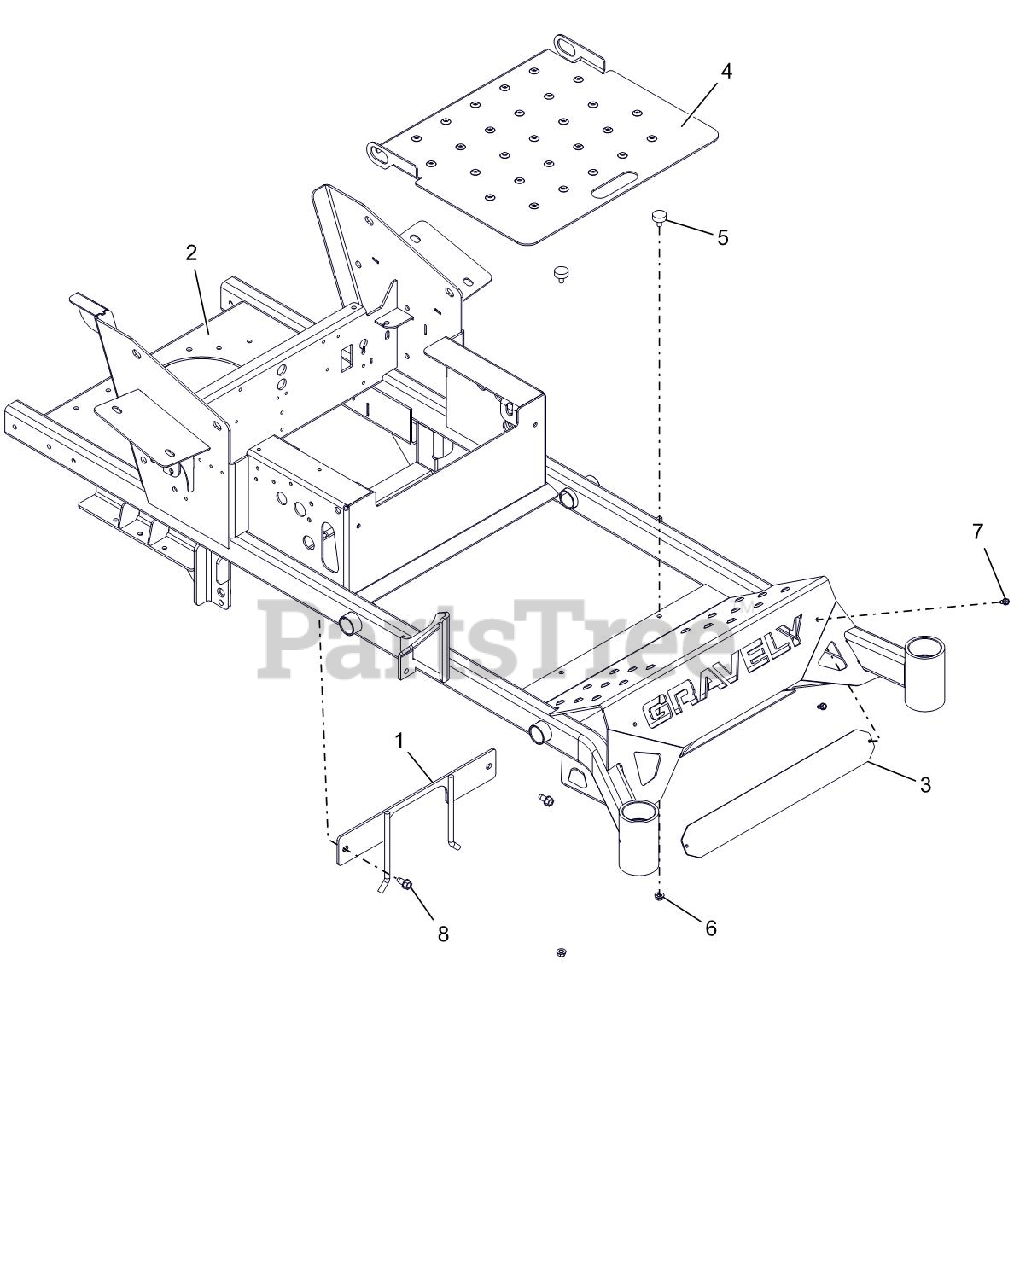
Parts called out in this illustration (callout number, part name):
1	PTO BELT FINGER WLDMT - BLK
2	PT/100 48-52 FRM W/SAFETY DECL
3	BUMPER LOGO BACKING PLATE -BLK
4	PT/100 FOOT PLT W/SAFETY DECAL
5	BUMPER, RUBBER
6	@NUT-SPNLK-FLG .312-18 YWZC
7	SCR-TAP .25-20X.50 HWH TR YWZ
8	@SCR-TAP .38-16X.75 HWH TR YWZ
